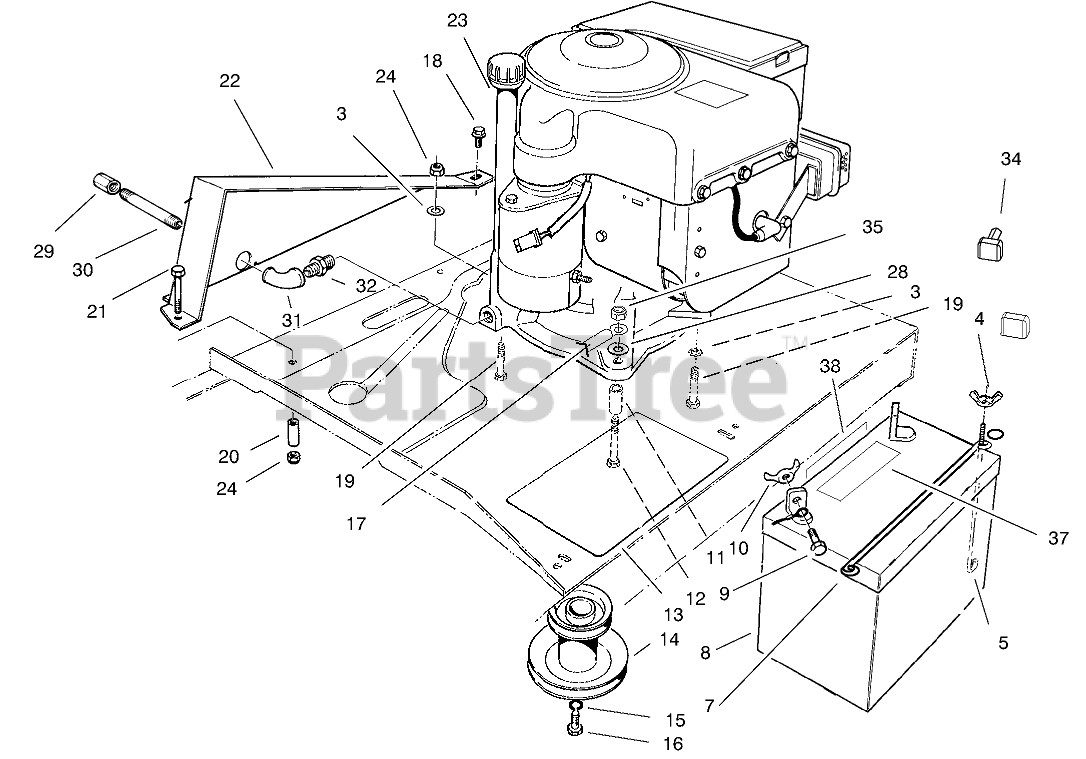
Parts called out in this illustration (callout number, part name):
3	WASHER-PLAIN
4	NUT-WING
5	POST-BATTERY
7	ROD-BATTERY HOLD DWN
8	BATTERY-155 CCA
9	SCREW-HH
10	NUT-WING
11	SPACER-PIVOT
12	SCREW-HH
13	PAD-SKID, ANTI
14	PULLEY - ENGINE
15	WASHER-FLAT
16	SCREW-HH
17	ASM - CABLE WIRE
18	SCREW-HWHTF
19	SCREW-HH
20	GUIDE-BELT
21	SCREW-HH
22	GUIDE-CHAIN
23	Engine-8 H.P. B and S
24	NUT-LOCK, NI
28	WASHER-LOCK
29	CAP-PIPE
30	NIPPLE-PIPE
31	ELBOW-STREET
32	BUSHING-PIPE
34	BOOT-TERMINAL
35	NUT-HEX, SIDE DEFORM
37	Decal-Battery
38	Decal-Battery
